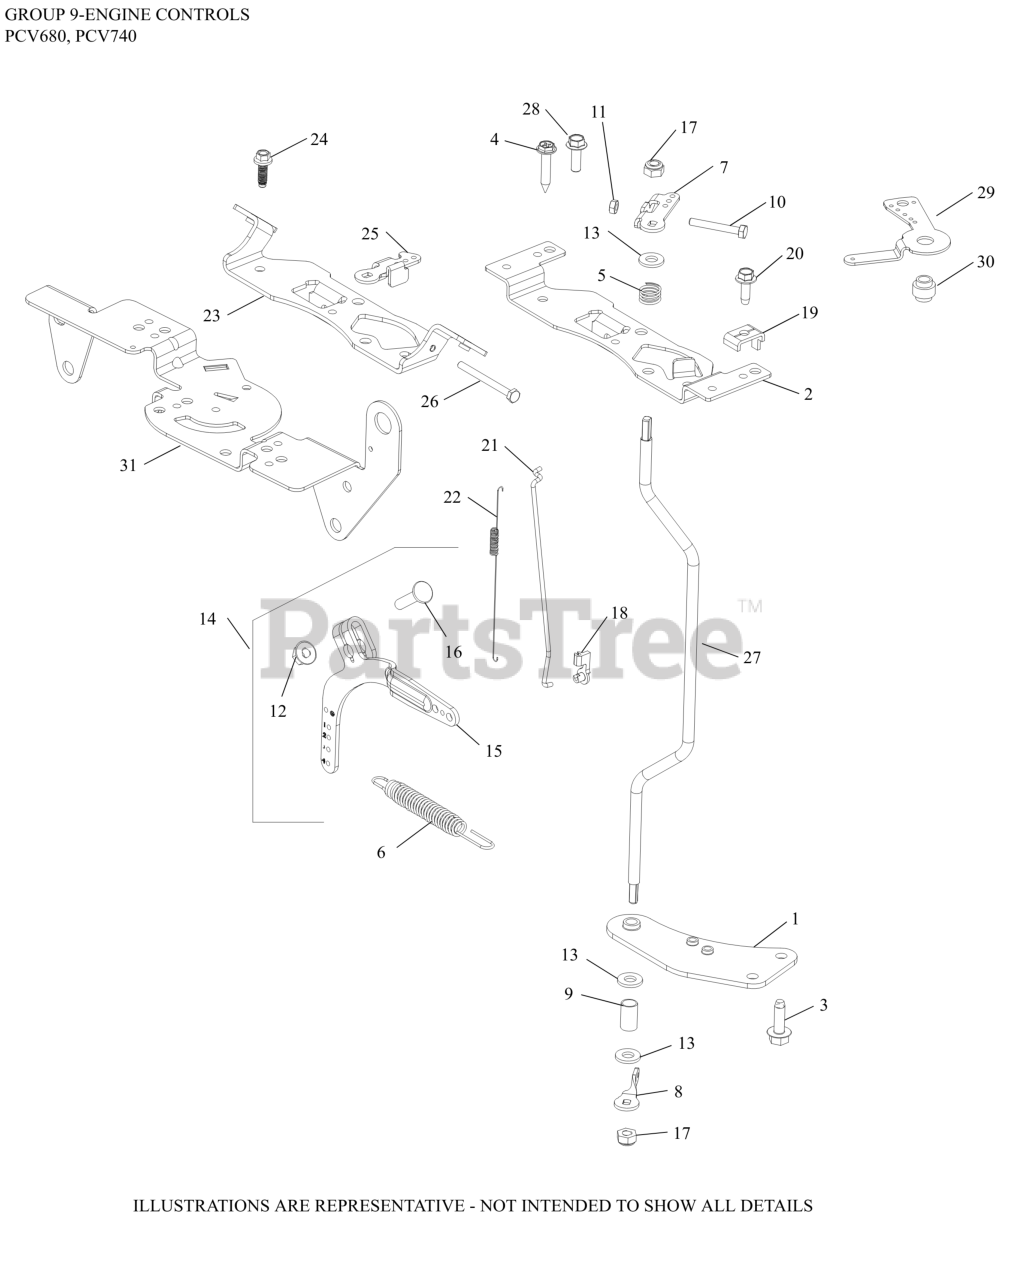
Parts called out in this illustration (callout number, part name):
1	BRACKET, THROTTLE SHAFT
3	SCREW, THREAD FORMING
5	SPRING, THROTTLE SHAFT
6	SPRING, GOVERNOR (RED)
8	LEVER, THROTTLE CONTROL
12	NUT, LOCK M6X1.0
13	WASHER, FLAT 1/4"
14	LEVER, GOVERNOR ASSEMBLY
15	LEVER, GOVERNOR - (#2409069S)
16	BOLT, RD HD SQ NECK M6X1.0X25
17	NUT, FLG M6X1.0
18	BUSHING, THROTTLE LINKAGE
19	CLAMP, CABLE-(#2523753S)
20	SCREW, THREAD FORMING
21	LINKAGE, THROTTLE
22	SPRING, LINKAGE
23	BRACKET, CONTROL
25	LEVER, THROTTLE CONTROL
26	SCREW, HEX HEAD
27	THROTTLE CONTROL SHAFT
28	SCREW, HI-LOW
